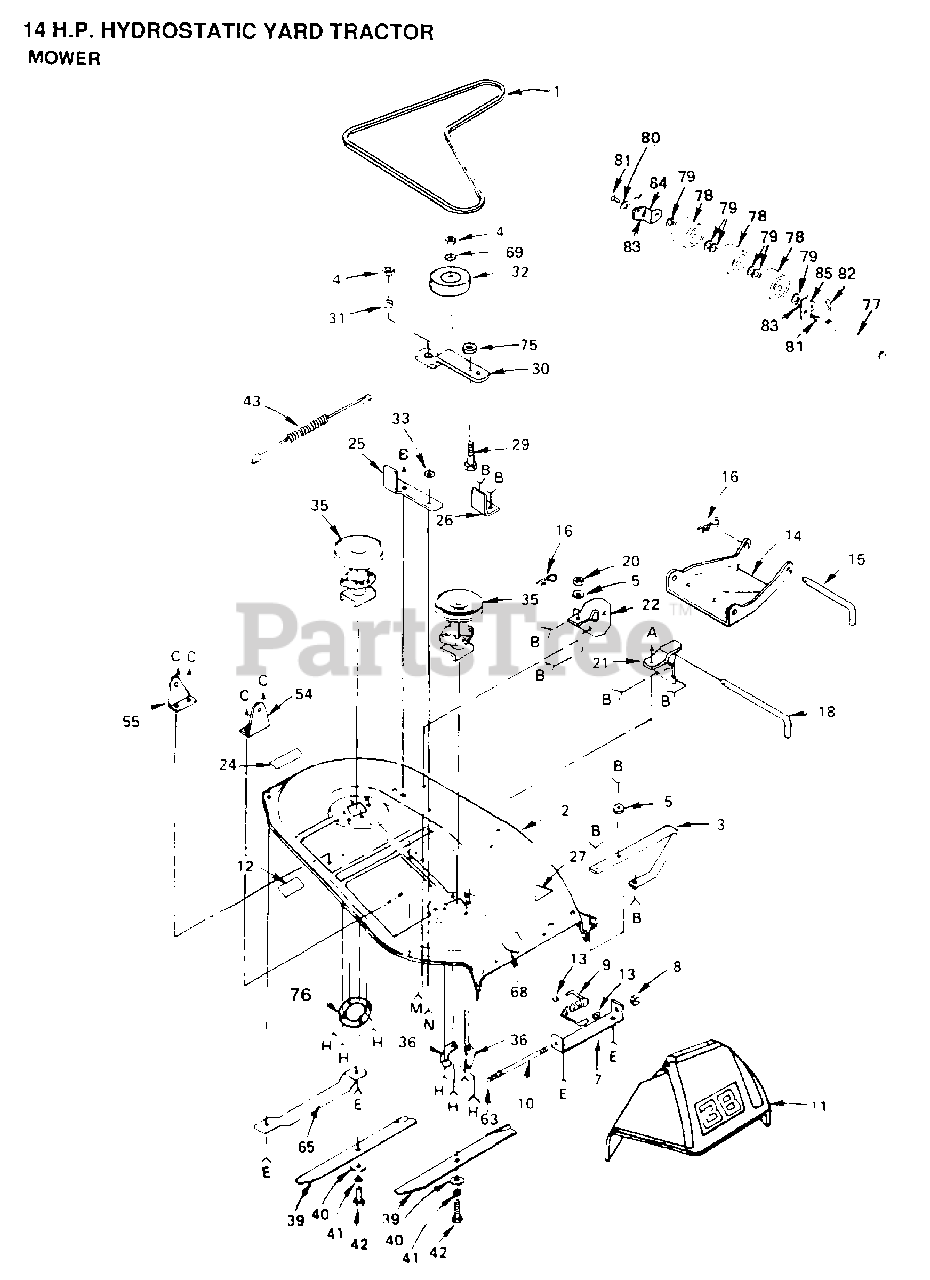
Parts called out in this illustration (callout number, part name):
5	WASHER M
8	NUT PUSH M
10	ROD-HINGE T
11	DEFLECTOR-SHLD T
13	CAP-SLEEVE LT
14	LINK.PARALLEL
15	"ROD, FRT. PARAL T"
16	SPRING.RETAINER
18	HINGE PIN T
21	BRACKET RH LT
22	BRACKET LH T
24	DECAL YT
25	SUPPORT ARM T
26	STOP T
29	BOLT
31	SPACER RETAINER
32	PULLEY IDLER
33	"WASHER, WEAR LT"
35	"JACKSHAFT.38""LT"
36	SUPPORT PLATE LT
39	"BLADE.38"" HI-LI"
40	WASHER
42	BOLT.3/8-24X1-1/2
43	"SPRING.EXT.8.5"""
54	"BRKT,SUSP RH T"
63	WASHER
65	RUNNER-LH M
68	DECAL WARNING
69	WASHER
75	WASHER
76	SUPPORT T
76	PIVOT PIN T
78	ROLLER T
79	WASHER T
81	BOLT
82	COTTER PIN
84	BRACKET LH T
85	BRACKET RH T
